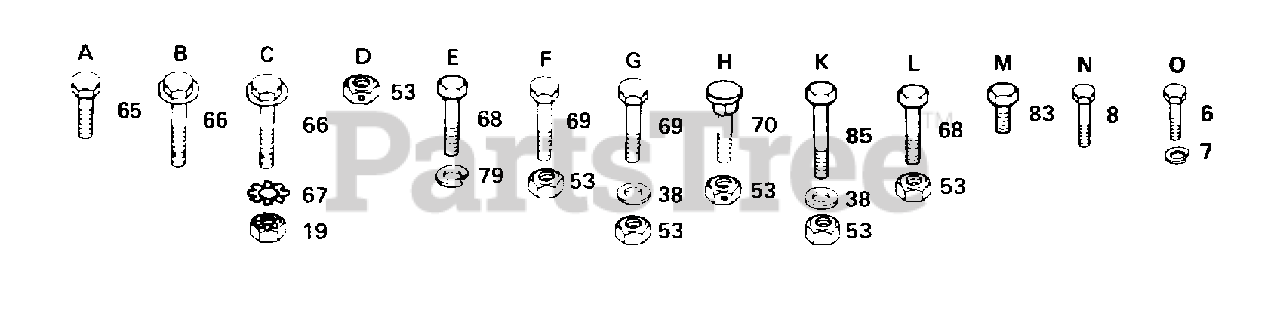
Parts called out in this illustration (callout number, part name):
6	BOLT
7	LOCKWASHER
19	NUT
38	WASHER
65	SCREW LT
66	SCREW LT
67	LOCKWASHER
69	BOLT
70	BOLT
79	LOCKWASHER
83	SCREW
85	BOLT
